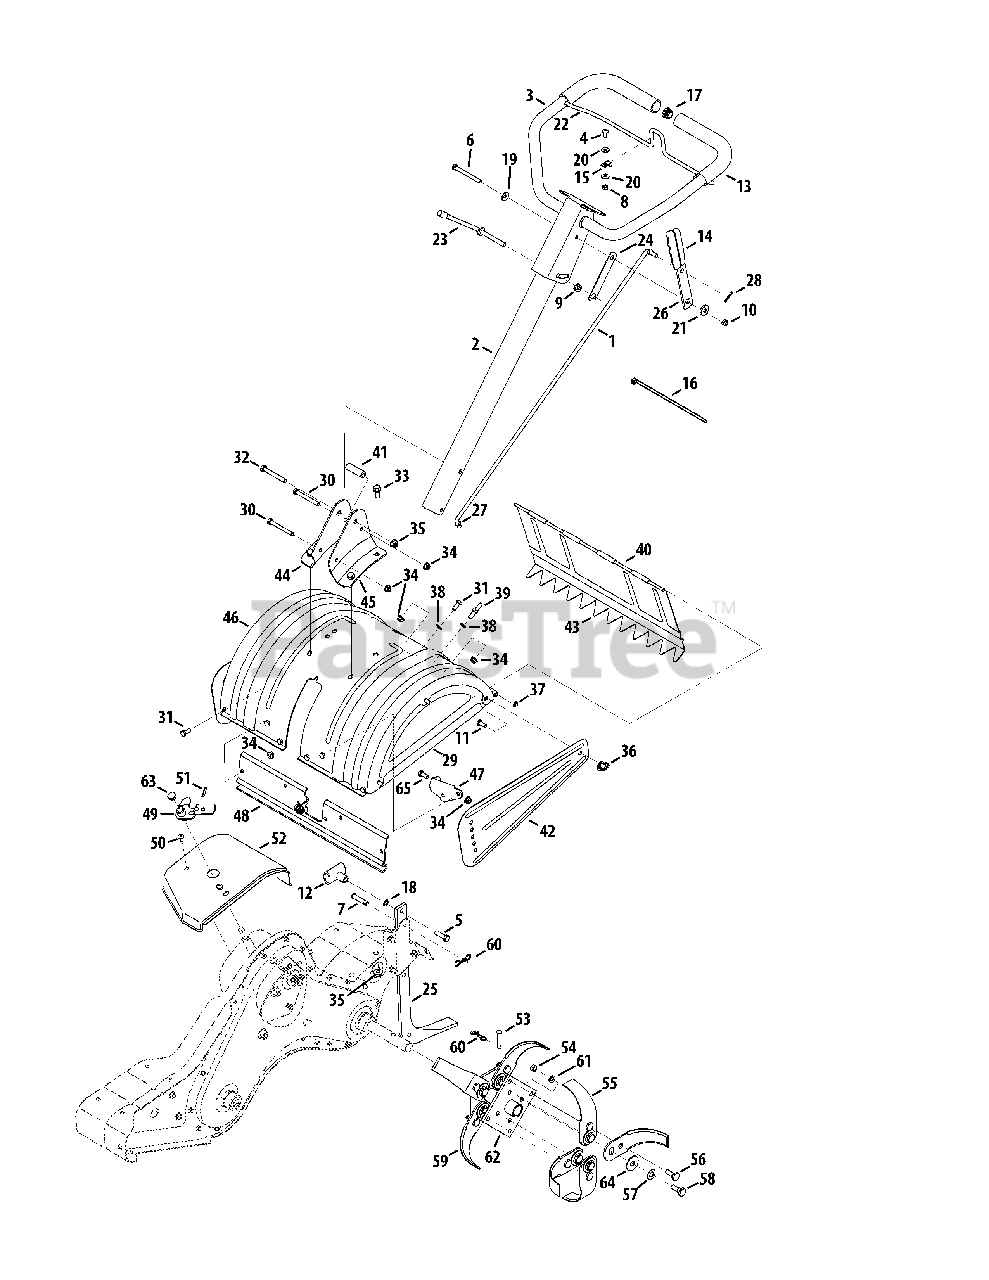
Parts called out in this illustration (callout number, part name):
1	Shaft Rod
2	Lower Handle Tube Assembly
3	Upper Handle Assembly
4	Screw, 1/4-20 x 0.625
5	Hex Head Screw, 3/8-16:1.25
6	Hex Head Screw, 5/16-18 x 3.25
7	Clevis Pin, .375 X 1.75
8	Hexlock Nut, 1/4-20
9	Flangelock Nut, 3/8-24
10	Hexlock Nut, 5/16-18
11	Stud, 5/16-18 x .75
12	Small Tee Knob
13	Foam Grip, .970 x 11.0
14	Grip, .1875 x 1.00
15	Battery Clamp, 5/16
16	Cable Tie, 8.5 LG
18	Washer, Flat, .385 x .620 x .033
19	Washer, Bell, .340 x .872 x .060
20	Washer, Flat, .260 x .720 x .060
21	Spacer, Shoulder, .50 x .190 x .360
23	Handle Adjustment Crank
24	Hex Nut Retainer Bracket
25	Tiller Depth Control
26	Shaft Rod Lever
27	Washer, Rubber, .33 ID x .125
28	Cotter Pin, .072 x 1.12 LG
29	End Cover Assembly
30	Hex Head Screw, 5/16-18 x 2.75
31	Hex Head Screw, 5/16-18 x .75
32	Hex Head Screw, 3/8-16 x 2.75
33	Hex Head Flange, 3/8-16 x .875
34	Flangelock Nut, 5/16-18
35	Flangelock Nut, 3/8-16
36	Wing Nut, 5/16-18 W/ Bell Washer
37	Speed Nut Cap, 1/4 ROD
38	Washer, Flat, .344 x .62 x .033
39	Screw, Hex, 5/16-18 x .75
40	Tiller Flap Rod
41	Spacer, .322 x .625 x 2.00
43	Rear Tine Shield
44	RH Handle Mount Bracket
45	LH Handle Mount Bracket
47	FRT Tine Shield Bracket
48	FRT Tine Shield Spacer Bracket
49	Shift Crank Assembly
50	Screw, 1/4-20 x .625
51	Spiral Pin, 3/16 x 1.0
53	Clevis Pin
54	Hex Nut, 3/8-24
55	13" Articulating Tine
56	Shoulder Bolt
57	Bell Washer, .515" ID x 1.14" OD
58	Shoulder Bolt
59	Tine Adapter Assembly, 18"
60	Internal Cotter Pin
61	Lock Washer
62	Tine Adapter Plate
64	Washer, Flat, .51 x 1.5 x .07
65	Hex Head Screw, 5/16-18 x 1.00
